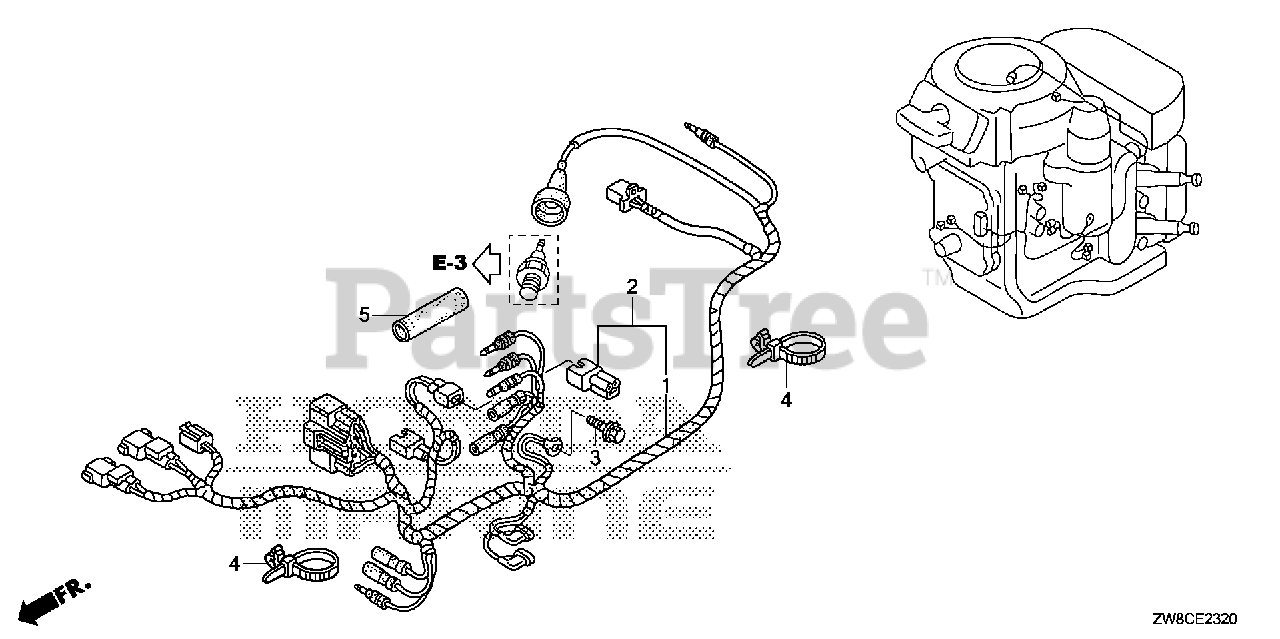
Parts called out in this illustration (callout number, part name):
2	WIRE HARNESS ASSY.
3	BOLT, FLANGE (6X12)
4	BAND, WIRE (95MM)
5	TUBE, RUBBER (11.5X14.5)
